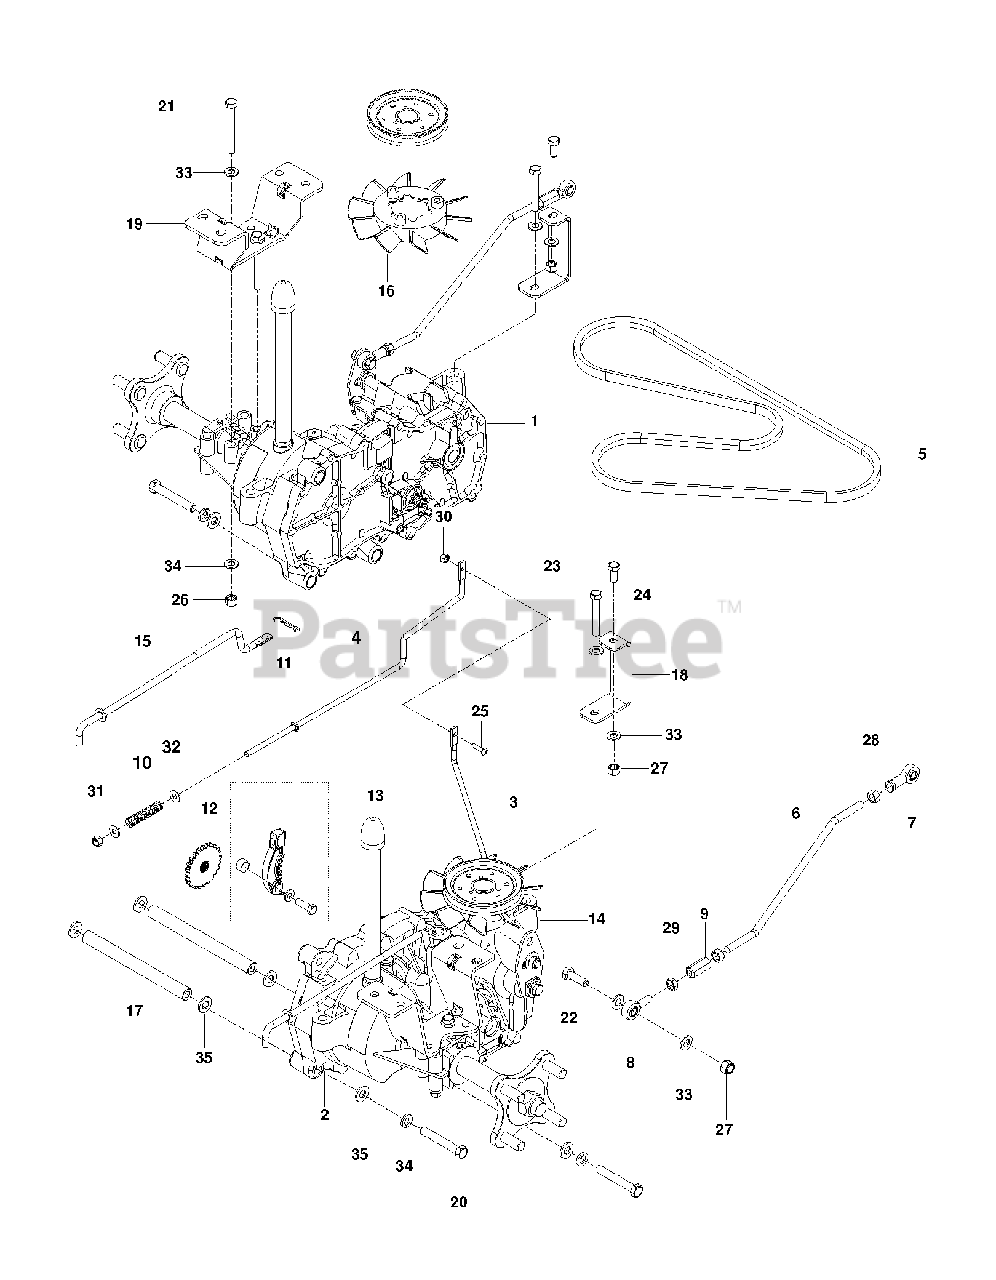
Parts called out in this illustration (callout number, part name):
1	HG_EZT, LT
2	HG_EZT, RT
3	LINKAGE.BRAKE.LT
4	LINKAGE, BRAKE RT
5	BELT, HYDRO PUMP
6	ROD, MOTION CONTROL
7	RH ROD END
8	RB ROD.END.LH
9	ROD END COUPLER
11	HAIRPIN #2
12	HG_DISC COG BRAKE 51635
13	HG_KIT BRAKE ARM (EZT)
14	HG_KIT, HYDRO-GEAR HUB
15	LINKAGE, BYPASS, EZT
16	HG_HYDRO FAN 51365
17	SPACER TUBE, EZT
18	SUPPORT.FRONT.TRANS.BLACK.
19	EZT MOUNT, REAR, BLACK
20	HCS 3/8C X 2 1/2
22	BOLT.FIN.HEX.5/16-18UNC X 1.00
23	HCS 5/16C X 3/4
24	BOLT.FIN HEX 5/16-18UNC X2 1/4
25	SCR #10-24 X 3/4
26	NUT.71038.31-18.HEX.NYLOCK
27	5/16-18 THIN PROF NY
29	NUT 5/16F LEFTHAND
30	NUT 10-24 NYLOC
31	LOCKNUT.NYLOC.1/4-20
33	WASHER
34	LOCKWASHER
35	WASHER
